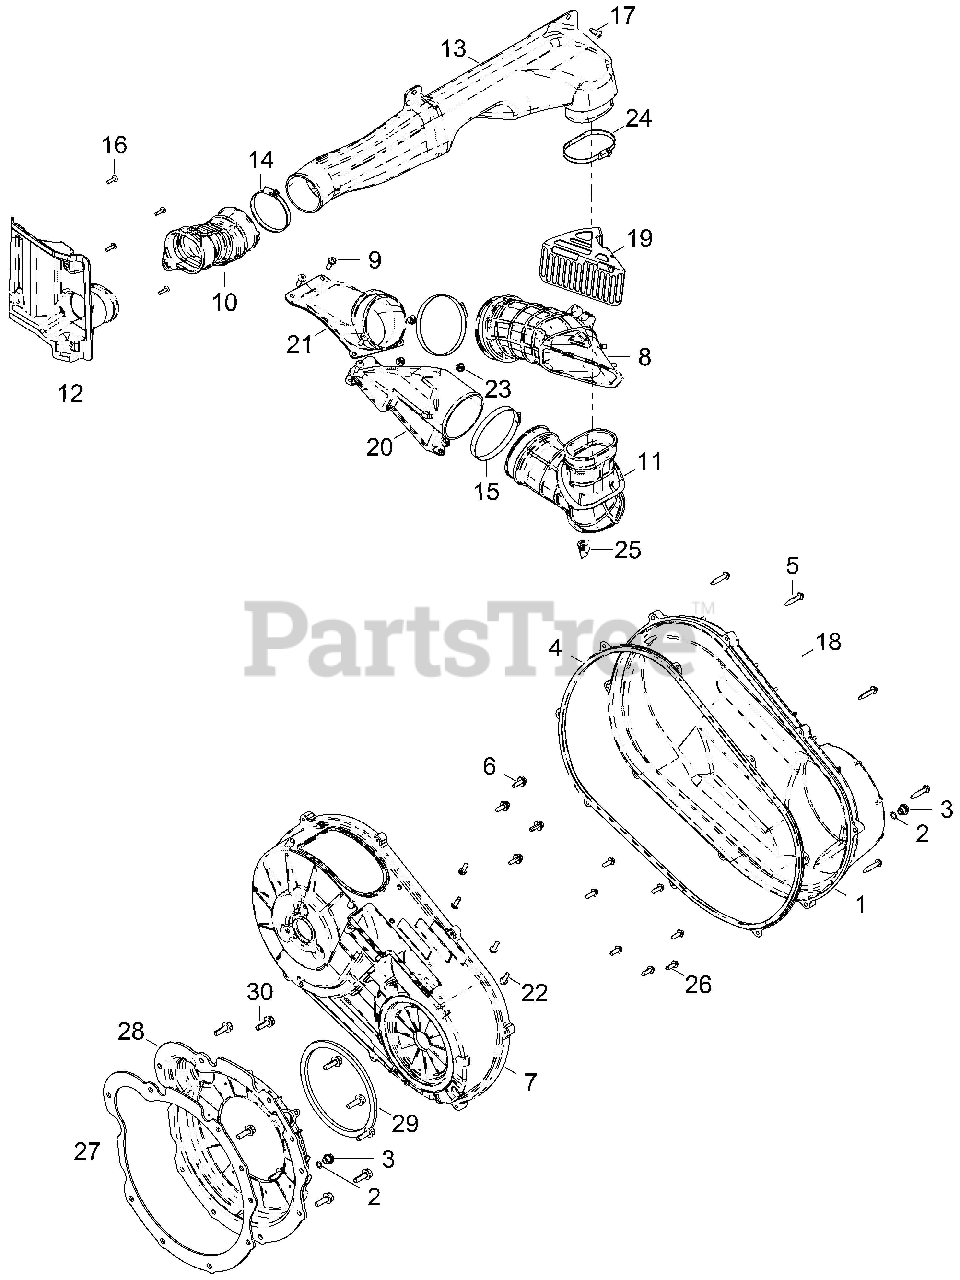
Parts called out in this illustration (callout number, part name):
1	ASM-COVER,CLUTCH,OUTER DSL
2	O RING-.364X.504X.07
3	PLUG-DRAIN
4	SEAL-OUTER CLUTCH COVER
5	SCR-HXFL-M6X35 ZOD HILO
6	ASM-BOLT/WASHER,20 MM
7	ASM-COVER,CLUTCH,INNER DSL
8	HOSE, CLUTCH, AIR OUTLET
9	SCR-#14X3/4 HI/LO-PH-PN TRX-M
10	HOSE-INTAKE,CLUTCH
11	HOSE-CLUTCH,AIR INLET
11	HOSE-CLUTCH,AIR IN,TRAP,900/1K
12	INTAKE-FENDER-REAR
13	DUCT-INTAKE,CLUTCH
14	CLAMP,BAND,NARROW (10)
15	CLAMP-WORM DRIVE,3.69 DIA
16	SCR-10X5/8-HI/LO,PN-T25,TRX-M
17	SCR-TX TRUSS-#14X3/4,HI/LO ZBK
18	DECAL, BELT, CAUTION/CHECK
19	BRKT-SCREEN,BELT
20	DUCT-CLUTCH,AIR INLET
21	DUCT, AIR OUTLET
22	SCR-M6X1.0X20MM,TX,PH,8.8-B
23	NUT-HXFL-M6X1.0 8 ZB3 NYL
24	CLAMP-BAND,NARROW 70-90MM
25	PLUG-DRAIN
27	SEAL-FLYWHEEL COVER
28	ASM-COVER-FLYWHEEL
29	SEAL-CLUTCH COVER,INNER
30	BOLT-M8X1.25X25,HXFLG-OLIVE D
